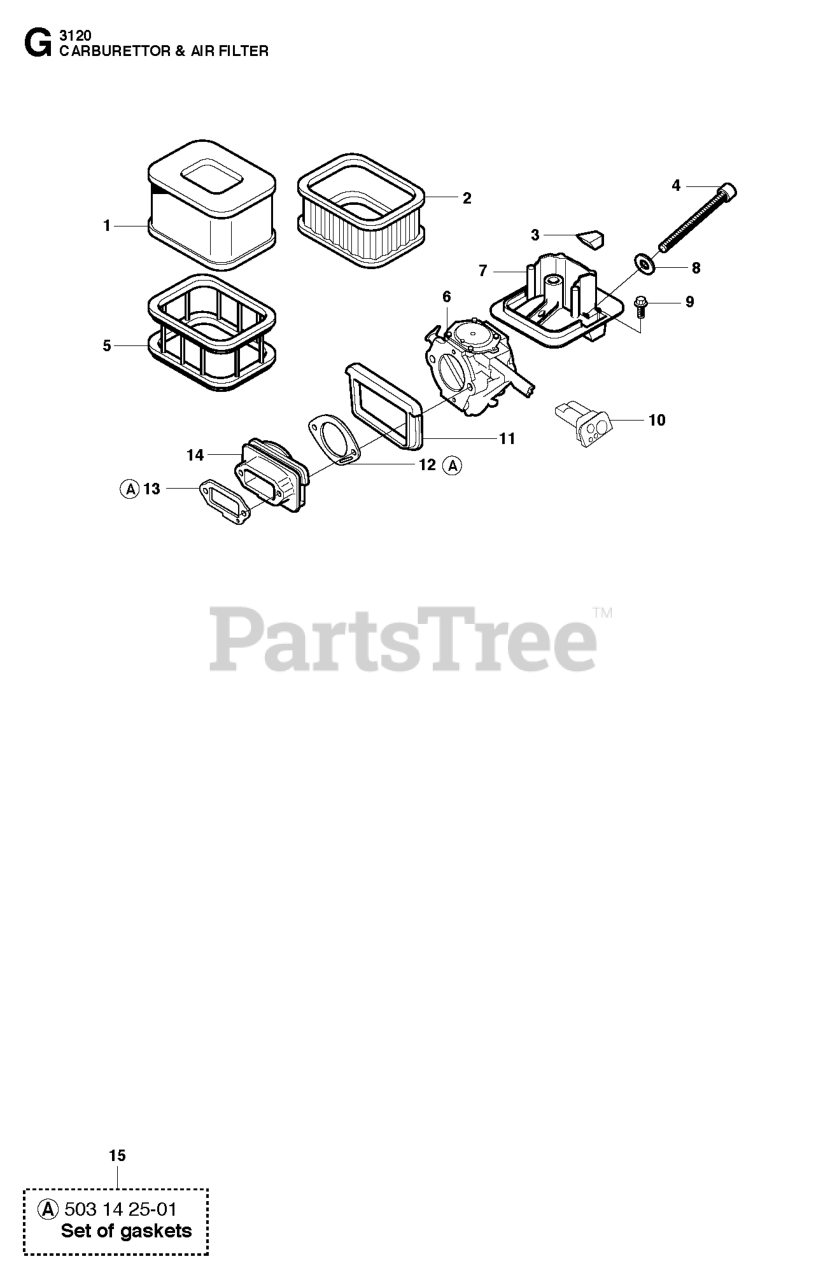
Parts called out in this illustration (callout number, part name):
1	AIRFILTER
2	AIR FILTER - FELT
5	FILTERHOLDER CPL
6	CARBURETOR WG7 EPA
6	CARBURETOR
7	FILTER HOLDER
8	WASHER
15	GASKET SET
